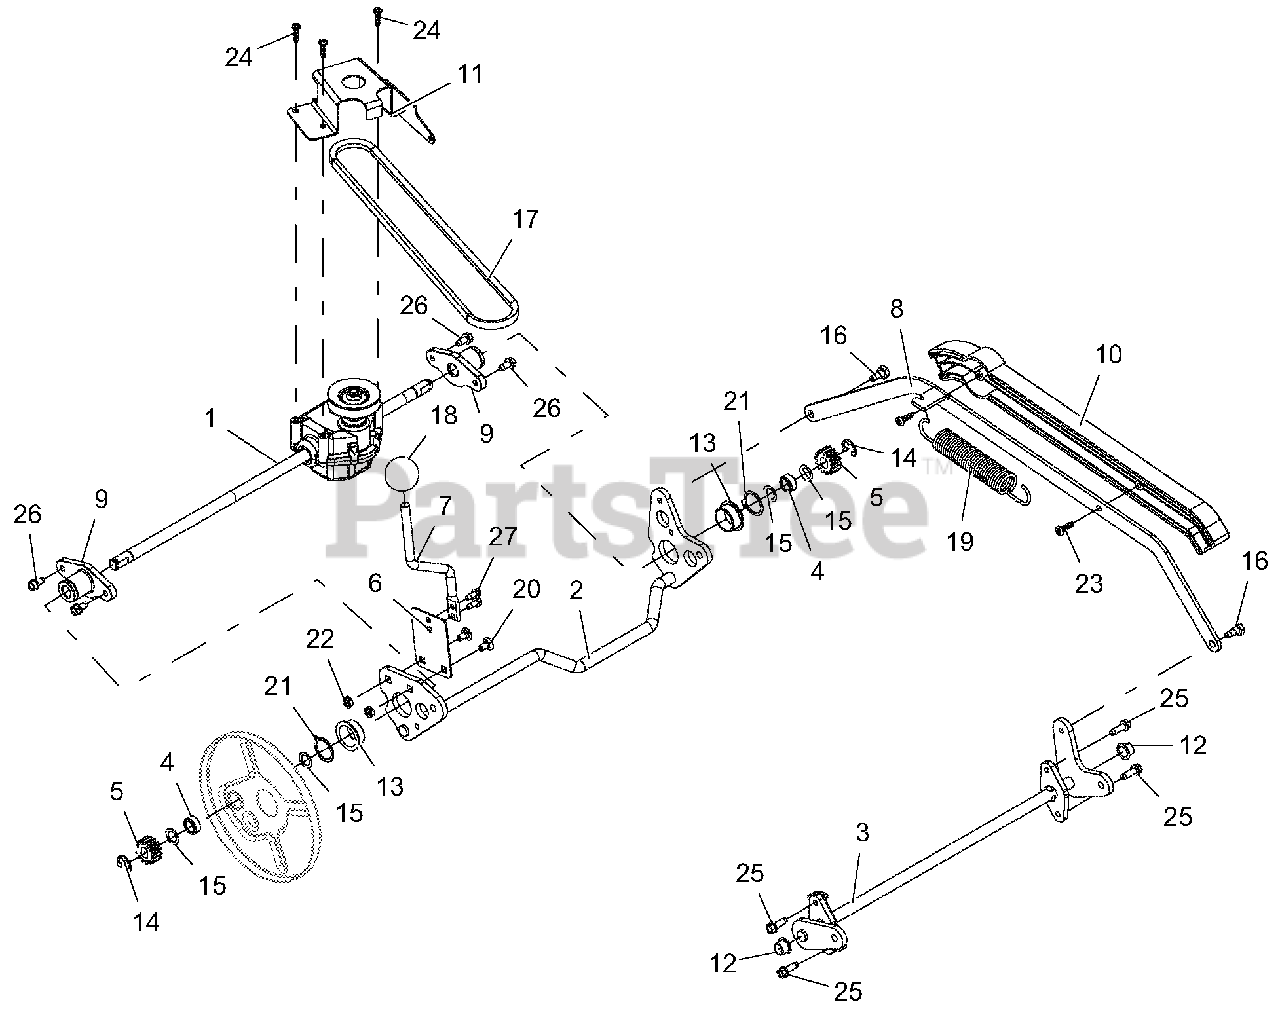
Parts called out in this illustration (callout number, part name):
1	TRANSAXLE, AUTOMATIC, LM, 9:1
2	WLDMT, LM REAR AXLE
3	WLDMT, LM FRONT AXLE
4	SPCR, PM .500ID X .75OD X .321
5	GEAR, PINION , LM WHEEL DRIVE
6	PLATE, HOC SPRING
7	LEVER, HOC ADJUST
8	LINK, HOC CONNECT
9	HUB, LM REAR AXLE
10	COVER, LINK ROD
11	BRKT, TRANS BELT GUIDE
12	BUSHING, POLYLINER - .50 SPLIT
13	BSHG, FLANGE 1.0x1.125x.50x1.375
14	RG-RTNG-EXT .500X.042 (E)
15	WASHER-FLAT-STL, .500 X .750 X .020
16	BOLT, SHLDR .320X.210X.25-20 SELF-TAPPING
18	KNOB,BALL -BLACK 1.47" .375-16
19	SPRG, EXTENSION
20	BLT-RDHDSQNK .25-20X.50 G5 Y
21	RG-RTNG-EXT 1.00X.042
22	@NUT-LK-CTR-JAM .25-20 YWZC
23	SCR-TAP #12-14X.75 PLASTITE BLZC
24	SCR-TAP #10-14X.75 PLASTITE BLZC
25	SCR-TAP .25-20X.75 HWH TR YWZ
26	SCR-TAP .25-20X.50 HWH TR YWZ
27	SCR-TAP 12-24X.50 HWH TR YWZC
